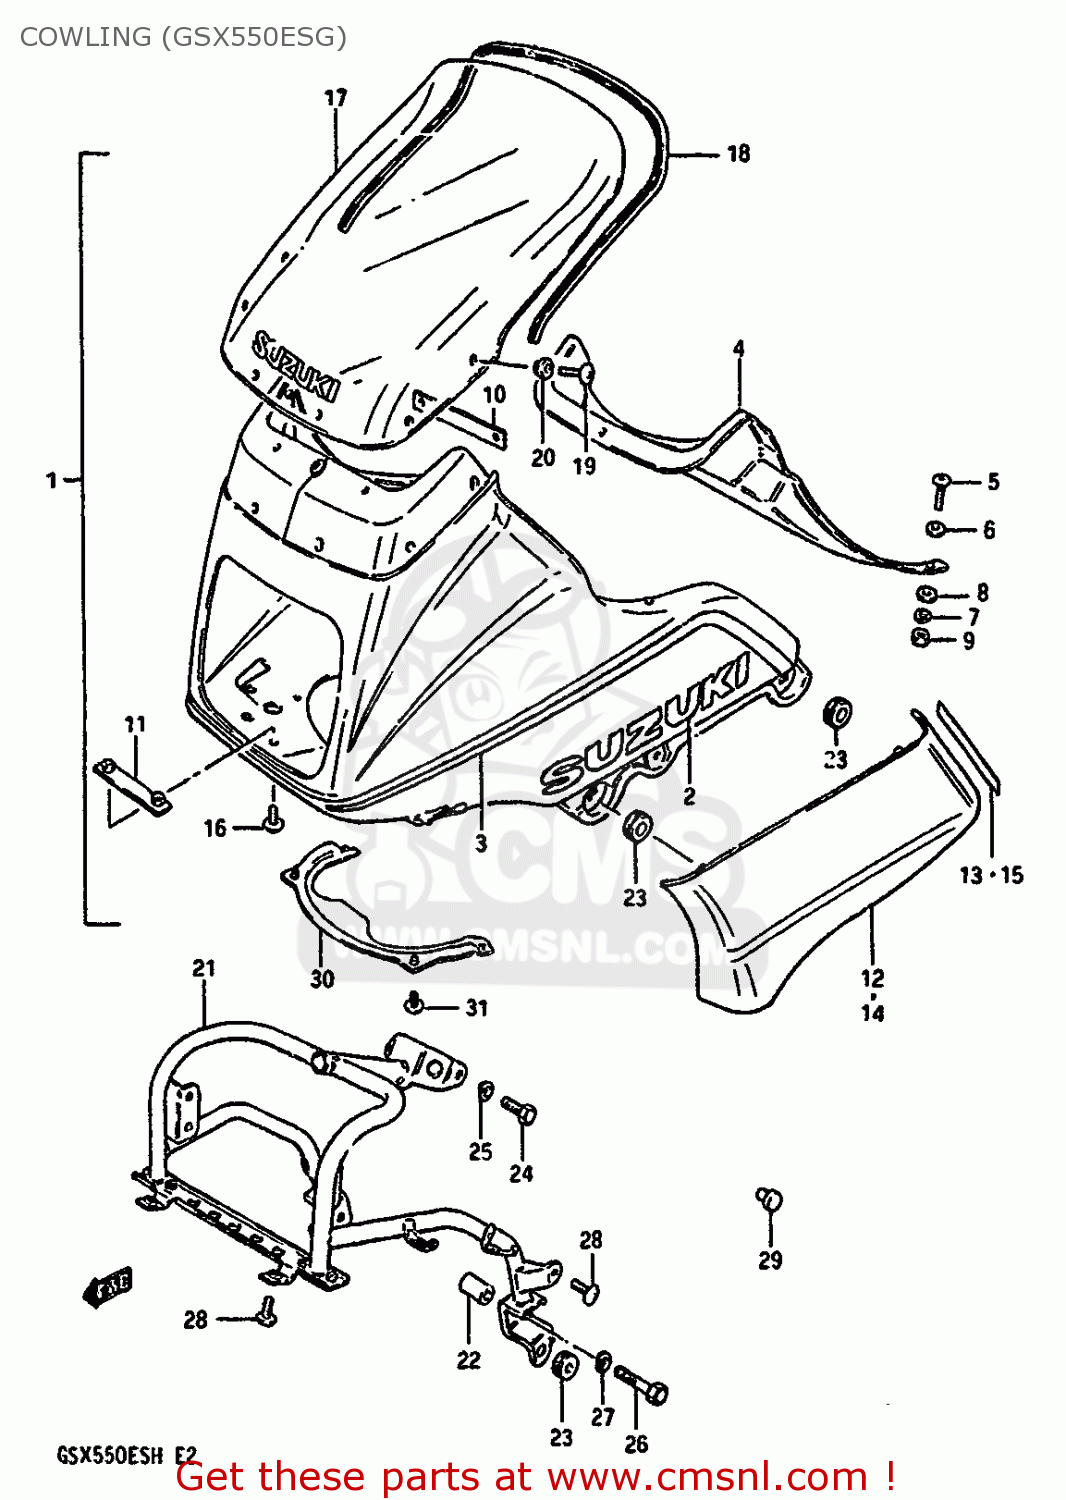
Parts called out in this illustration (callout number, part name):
1	BODY ASSEMBLY,COWLING
2	EMBLEM
3	TAPE SET
4	PANEL,COWLING,UPPER
5	SCREW
6	WASHER,5MM
7	WASHER,LOCK
8	WASHER,5MM
9	NUT ,5MM
10	BRACKET,COWLING,UPPER
11	BRACKET,COWLING,LOWER
12	COVER,COWLING
13	TAPE SET,COWLING
14	COVER,COWLING
15	TAPE SET,COWLING
16	SCREW
17	WINDOW
18	MOLDING,LOWER
19	SCREW
20	CUSHION
21	BRACE,COWLING
22	SPACER (8.2X12.5X23.5)
23	CUSHION
24	BOLT
25	WASHER,LOCK,8.
26	BOLT
27	WASHER,LOCK,8.
28	SCREW 6X12
29	PLUG
30	COVER,COWLING,LOWER
31	SCREW
